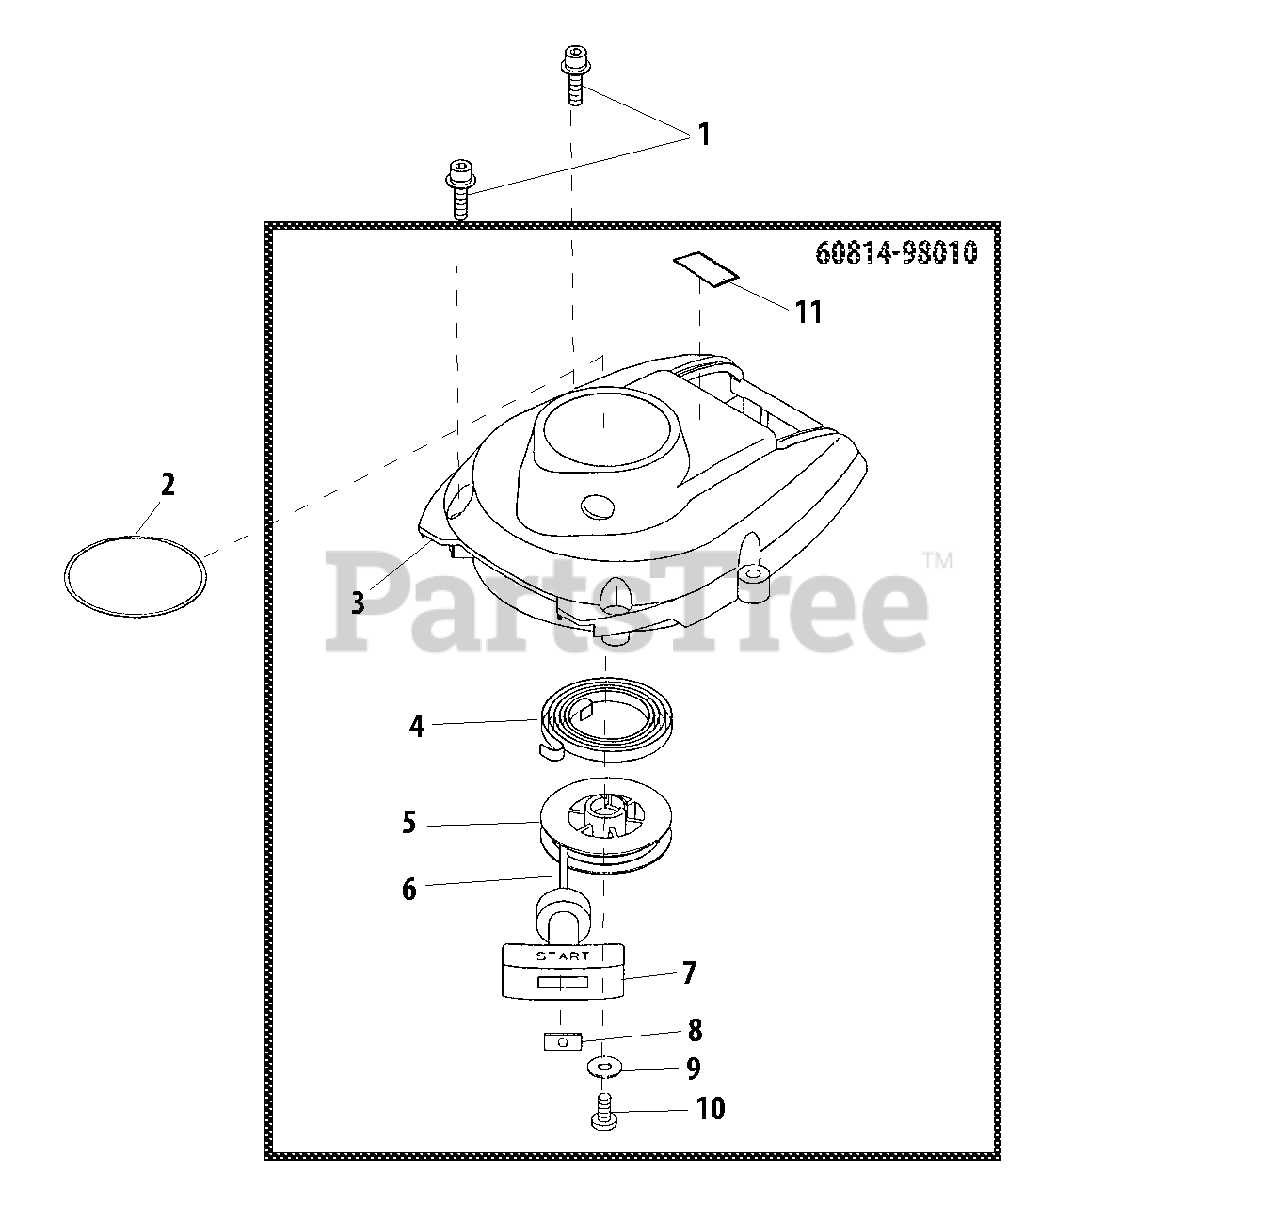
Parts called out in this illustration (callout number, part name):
1	SCREW - 5X20
2	LABEL - SHINDAIWA PROFESSIONAL
3	COVER, FAN
4	SPRING, REWIND
5	REEL, ROPE
6	ROPE, STARTER
7	GRIP, STARTER
8	RETAINER, ROPE
9	WASHER
10	SCREW
11	LABEL - CAUTION
60814-98010	STARTER ASSY
